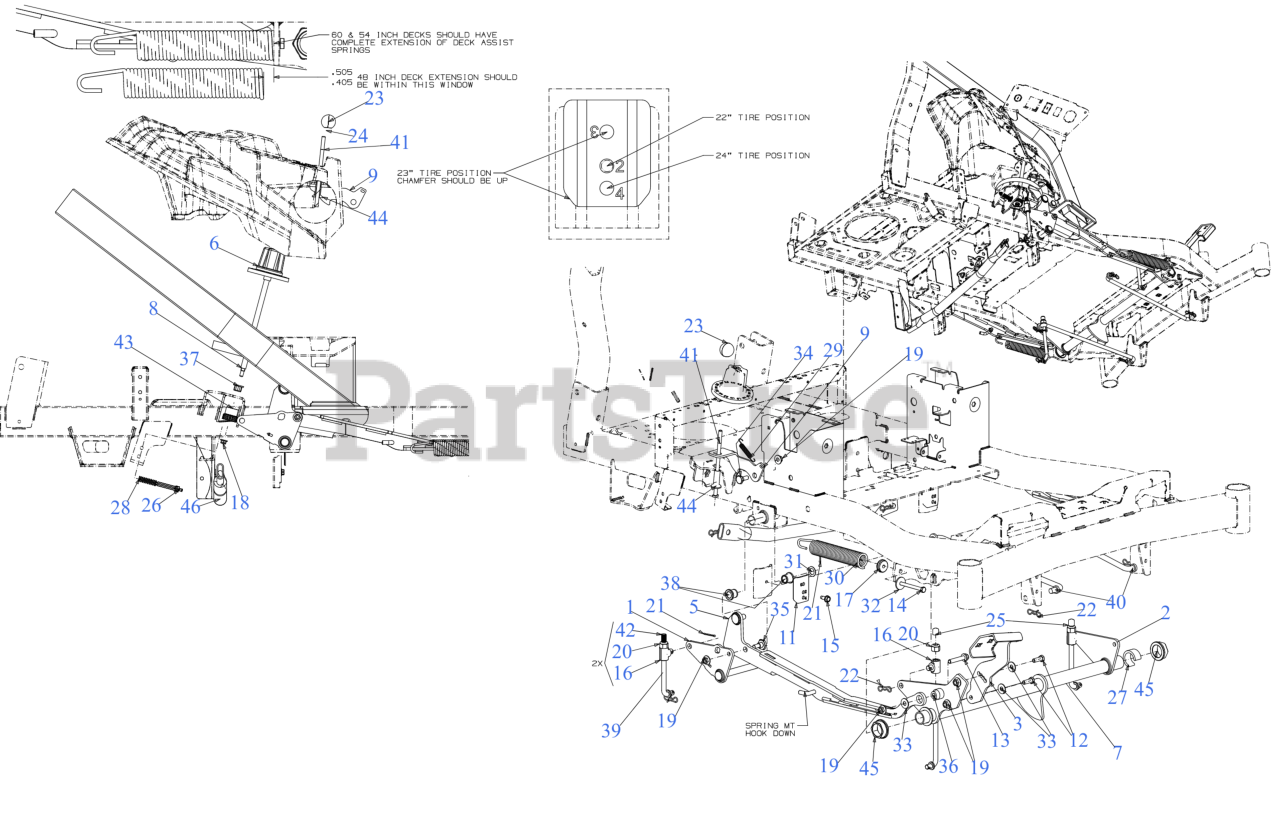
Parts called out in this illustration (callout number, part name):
1	BELLCRANK BRACKET (RH)
2	BELLCRANK BRACKET (LH)
3	DECK LIFT PEDAL
5	LIFT LINK (LH)
5	LIFT LINK (RH)
6	DECK HEIGHT ADJUSTMENT KNOB
7	LIFT TUBE (FRONT)
8	DECK HEIGHT ADJUSTMENT ROD
9	TRAVEL LOCK PLATE
11	UPSTOP BRACKET
12	SCREW 3/8-16 x 1 GR5
13	SCREW 3/8-16 x 2.00 GR5
14	SCREW 5/16-18 x 3.50 GR5
15	SCREW 5/16-18 x .750
16	LIFT ROD FERRULE
17	LIFT SPRING INSERT
18	FLANGE LOCK NUT 5/16-18
19	FLANGE LOCK NUT
20	HEX LOCK NUT NYLON
21	COTTER PIN
22	BOW TIE COTTER PIN
25	LIFT ROD END CAP
26	DETENT PLUNGER
27	LIFT TUBE SPACER
28	COMPRESSION SPRING .531 OD 1.75 LG
29	EXTENSION SPRING 2.675"
30	EXTENSION SPRING
31	FLAT WASHER
32	WASHER-5/16 x 1.25X 1.27
33	WASHER-.395 x 1.0 x .62
34	SHOULDER SCREW
35	SHOULDER SCREW .50 x .385
36	SHOLUDER SPACER
37	HEX FLANGE BEARING .506ID x .590LG
38	FLANGE BUSHING
39	DECK LIFT ROD 6.875"
40	DECK CONTROL ROD
41	TRAVEL LOCK ROD
42	DECK LIFT ROD 6.250"
43	DECK HEIGHT DETENT HUB
44	LOCK ROD SLEEVE SPACER
45	FLANGE BEARING
46	DECK STABILIZER TUBE
